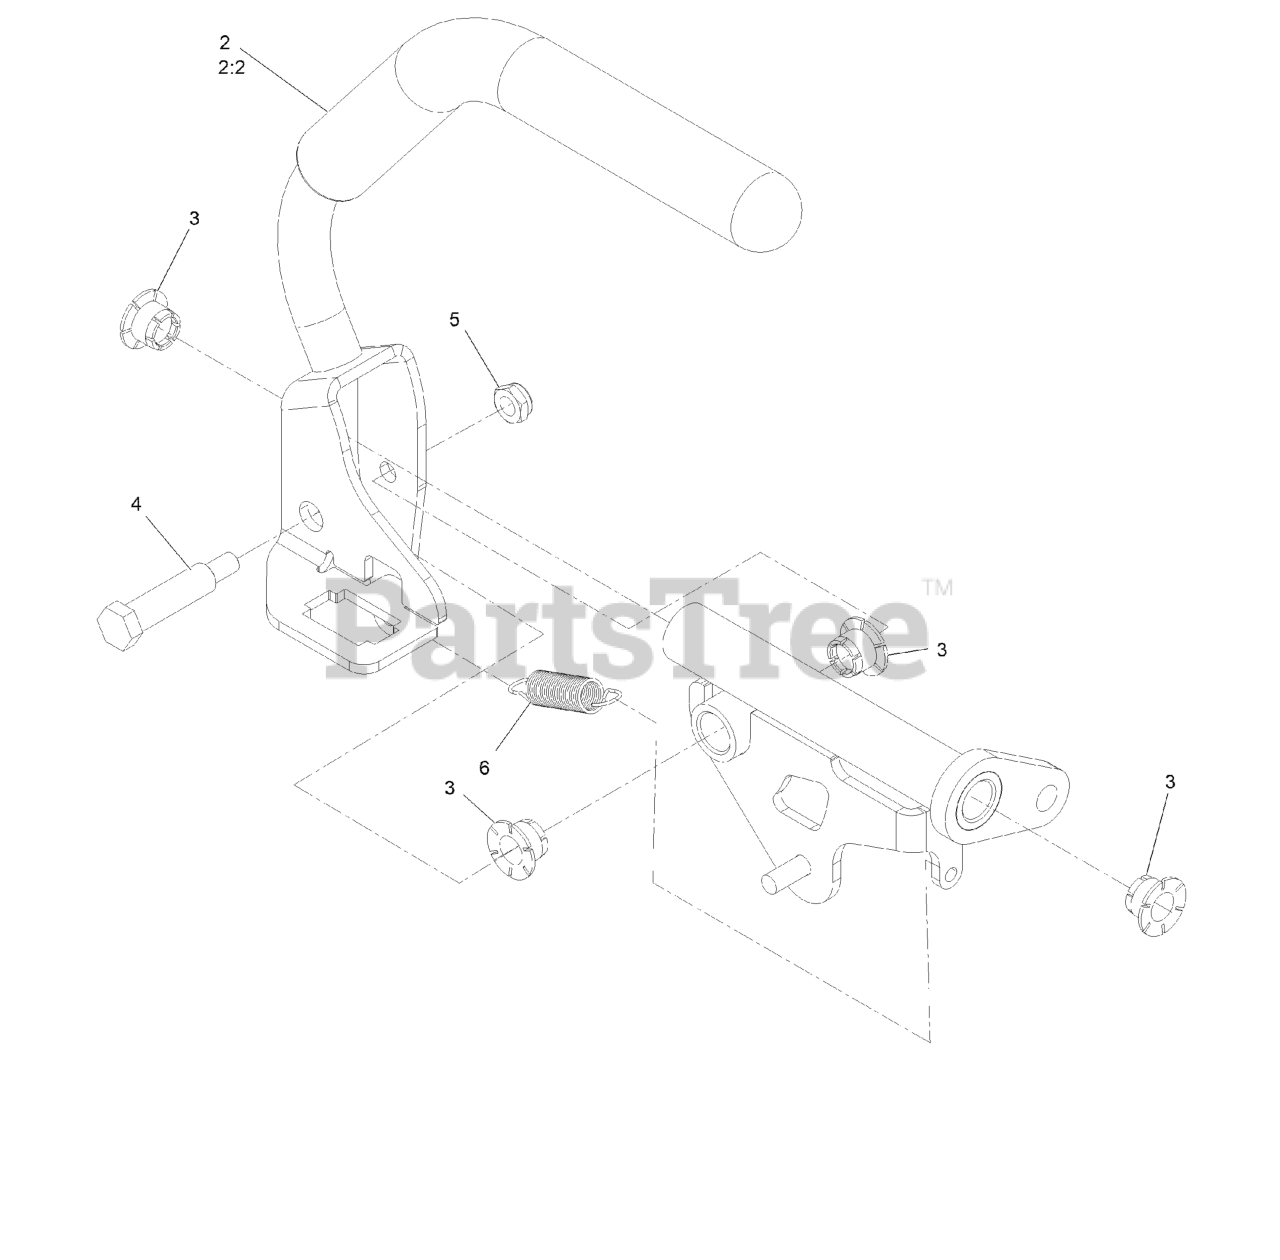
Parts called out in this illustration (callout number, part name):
2	ASM, RT CONTROL LEVER W/ GRIP
2:2	GRIP, DRIVE LEVER
3	BEARING, IGUS
4	BOLT-SHOULDER
5	NUT-LOCK, NI
6	SPRING-EXTENSION
